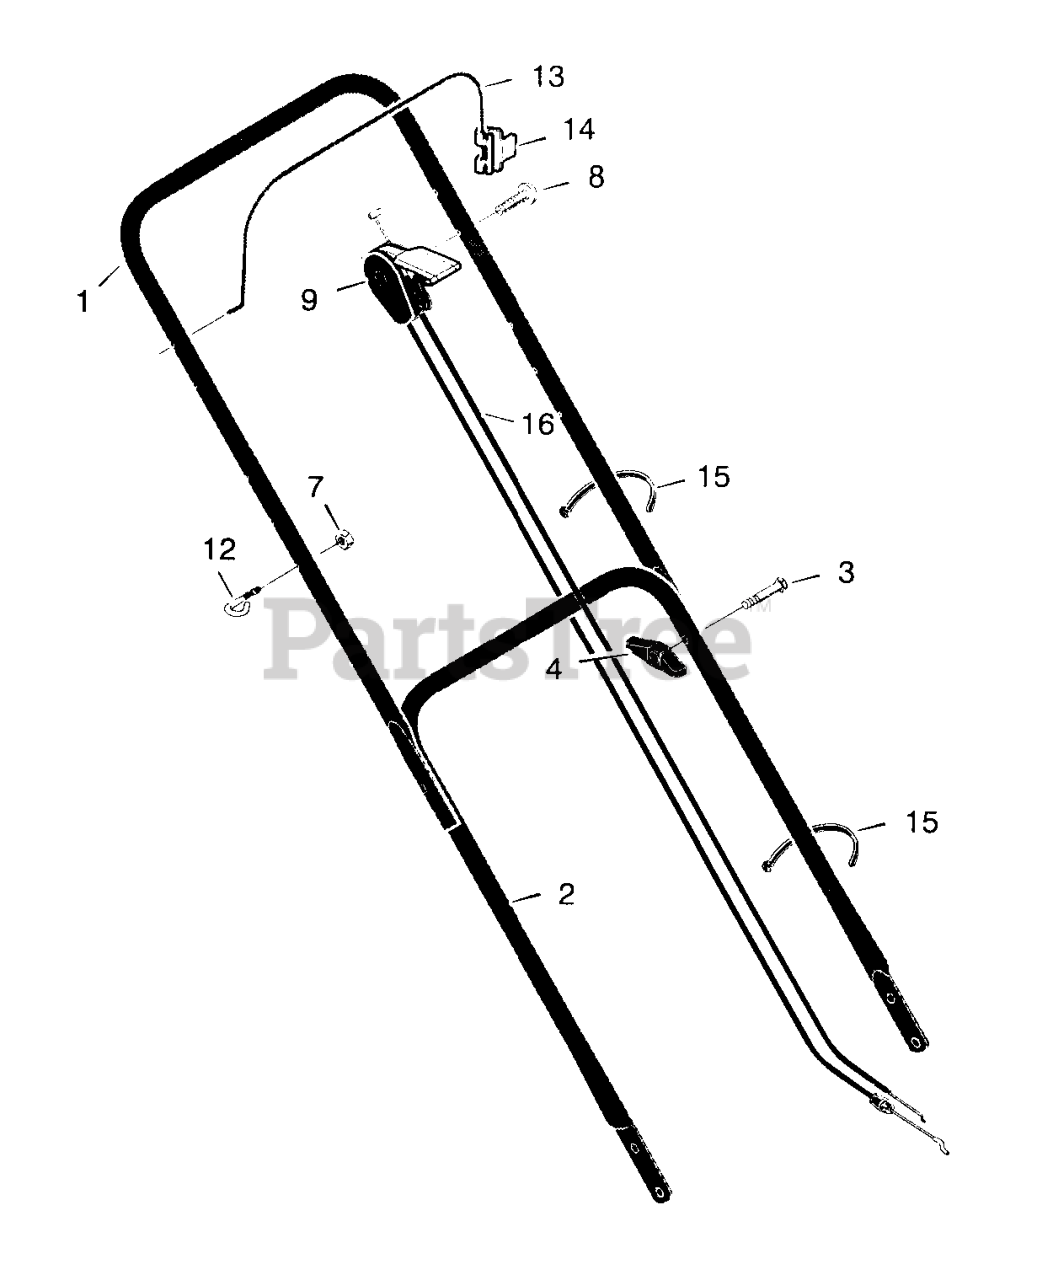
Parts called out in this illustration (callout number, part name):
1	Handle, Upper (Black)
2	Handle, Lower (Black)
4	Knob, Plastic
7	Locknut
9	Throttle Control
12	GUIDE, ROPE
13	Engine Stop Lever
14	Bracket, Stop Lever
15	Fastener, Cable
16	Engine Stop Cable
